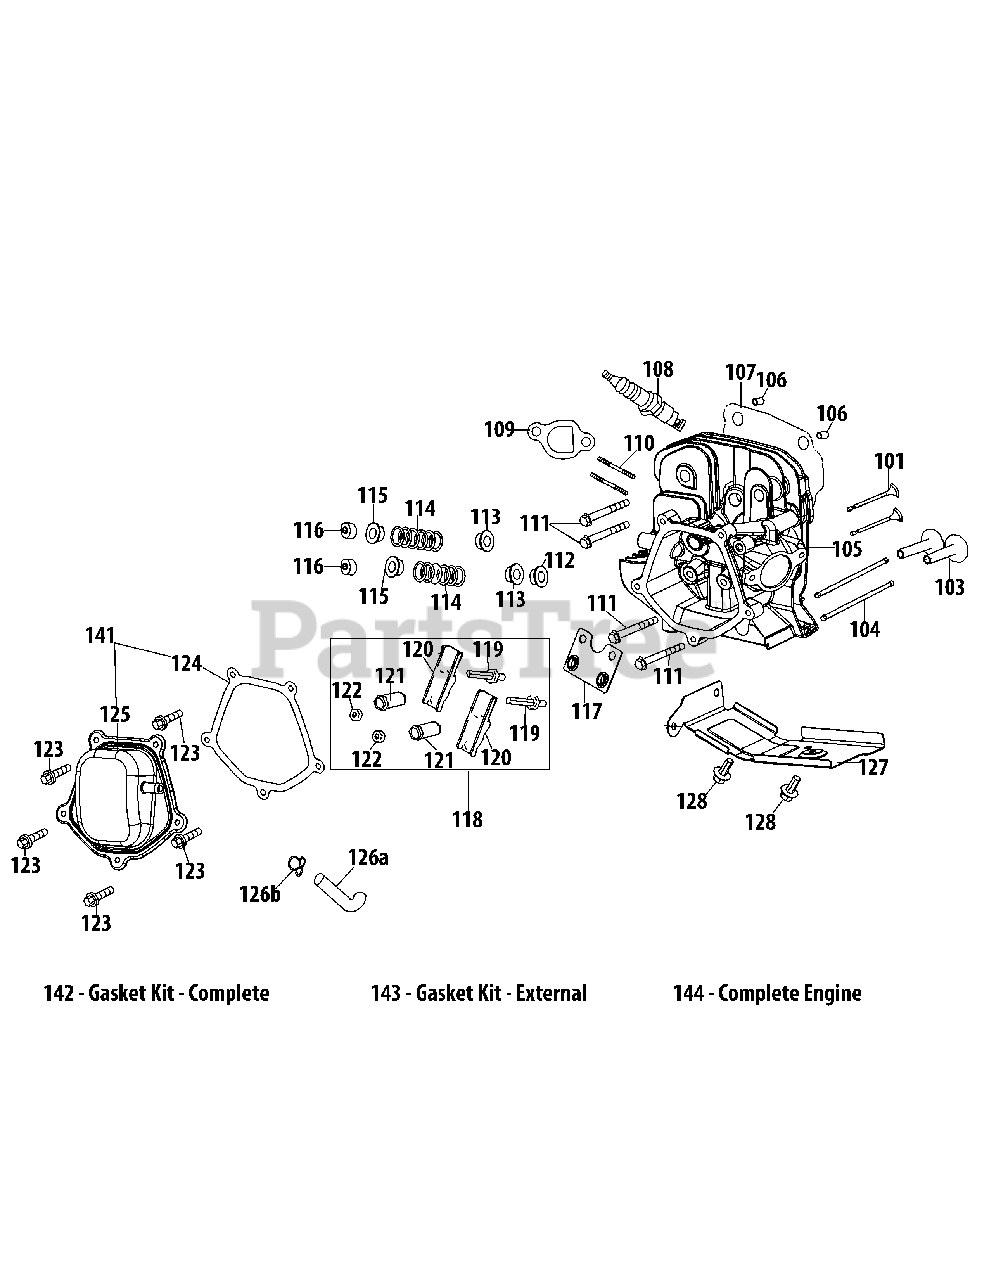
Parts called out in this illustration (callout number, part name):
103	Tappet
104	Push Rod Kit
105	Cylinder Head Kit
105	Cylinder Head Assembly
106	Dowel Pin 12×20
107	Gasket, Cylinder Head
108	Spark Plug/F6Rtc
109	Exhaust Pipe Gasket
110	Stud M8×48.5
110	Muffler Stud Assembly
111	Bolt M10×1.25×80
112	Valve Seal (Intake)
113	Valve Spring Retainer(Intake)
114	Valve Spring
115	Valve Spring Retainer
116	Exhaust Lash Cap
117	Push Rod Guide
118	Rocker Arm Assembly
119	Bolt, Pivot
120	Rocker Arm
121	Adjusting Nut ,Valve
122	Nut, Pivot Locking
123	Valve Cover Bolt
124	Valve Cover Gasket
125	Valve Cover
127	Air Shield
128	Bolt M6×12
141	Valve Cover Kit
142	Gasket Kit - Complete
143	Gasket Kit - External
144	Complete Engine
